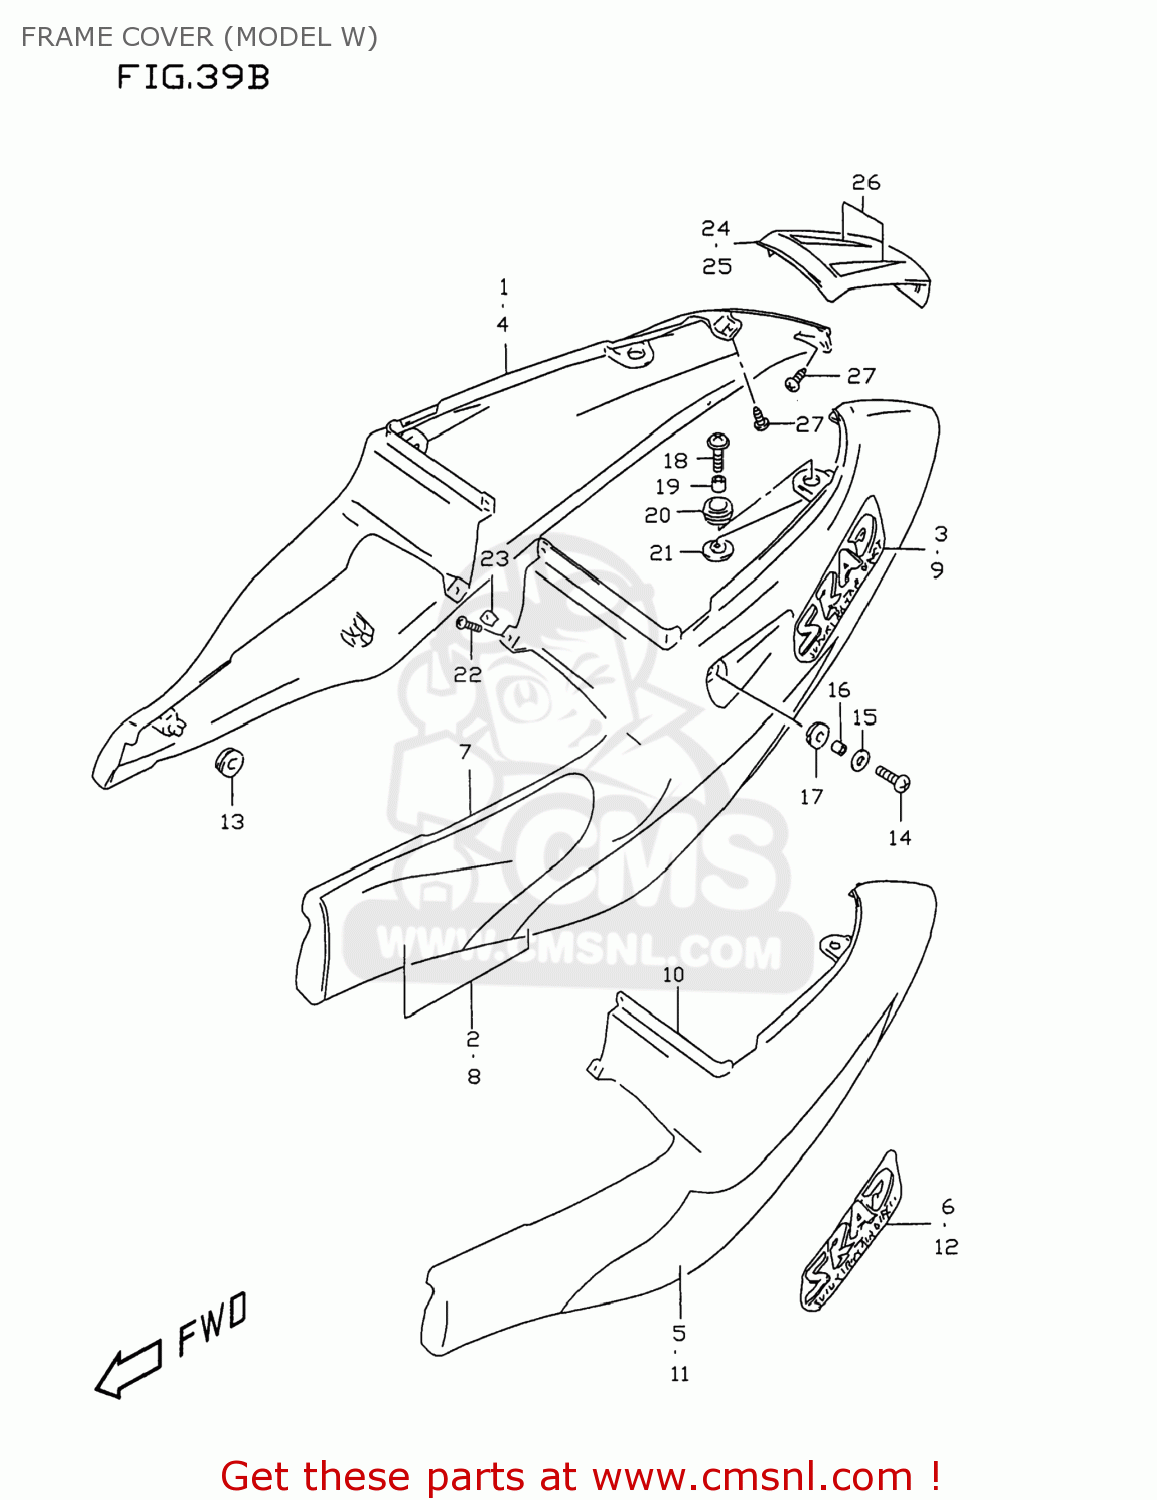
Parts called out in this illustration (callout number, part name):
1	COVER,FRAME,R(BRACK)
2	TAPE SET,FRAME COVER,R
3	EMBLEM,FRAME COVER
4	COVER,FRAME,R(WHITE)
5	TAPE,FRAME COVER,R(BLUE)
6	EMBLEM,FRAME COVER
7	COVER,FRAME,L(BRACK)
8	TAPE SET,FRAME COVER,L
9	EMBLEM,FRAME COVER
10	COVER,FRAME,L(WHITE)
11	TAPE,FRAME COVER,L(BLUE)
12	EMBLEM,FRAME COVER
13	CUSHION
14	SCREW(6X20)
15	WASHER(6.5X22X1.6)
16	SPACER(6.5X9X6.7)
17	CUSHION
18	SCREW(6X25)
19	SPACER(6.5X10X9.4)
20	CUSHION,TAIL COVER UPR
21	CUSHION,FRAME COVER LWR
22	SCREW
23	NUT
24	COVER,FRAME CTR
25	COVER,FRAME CTR
26	TAPE SET,FRAME COVER CTR
27	SCREW
